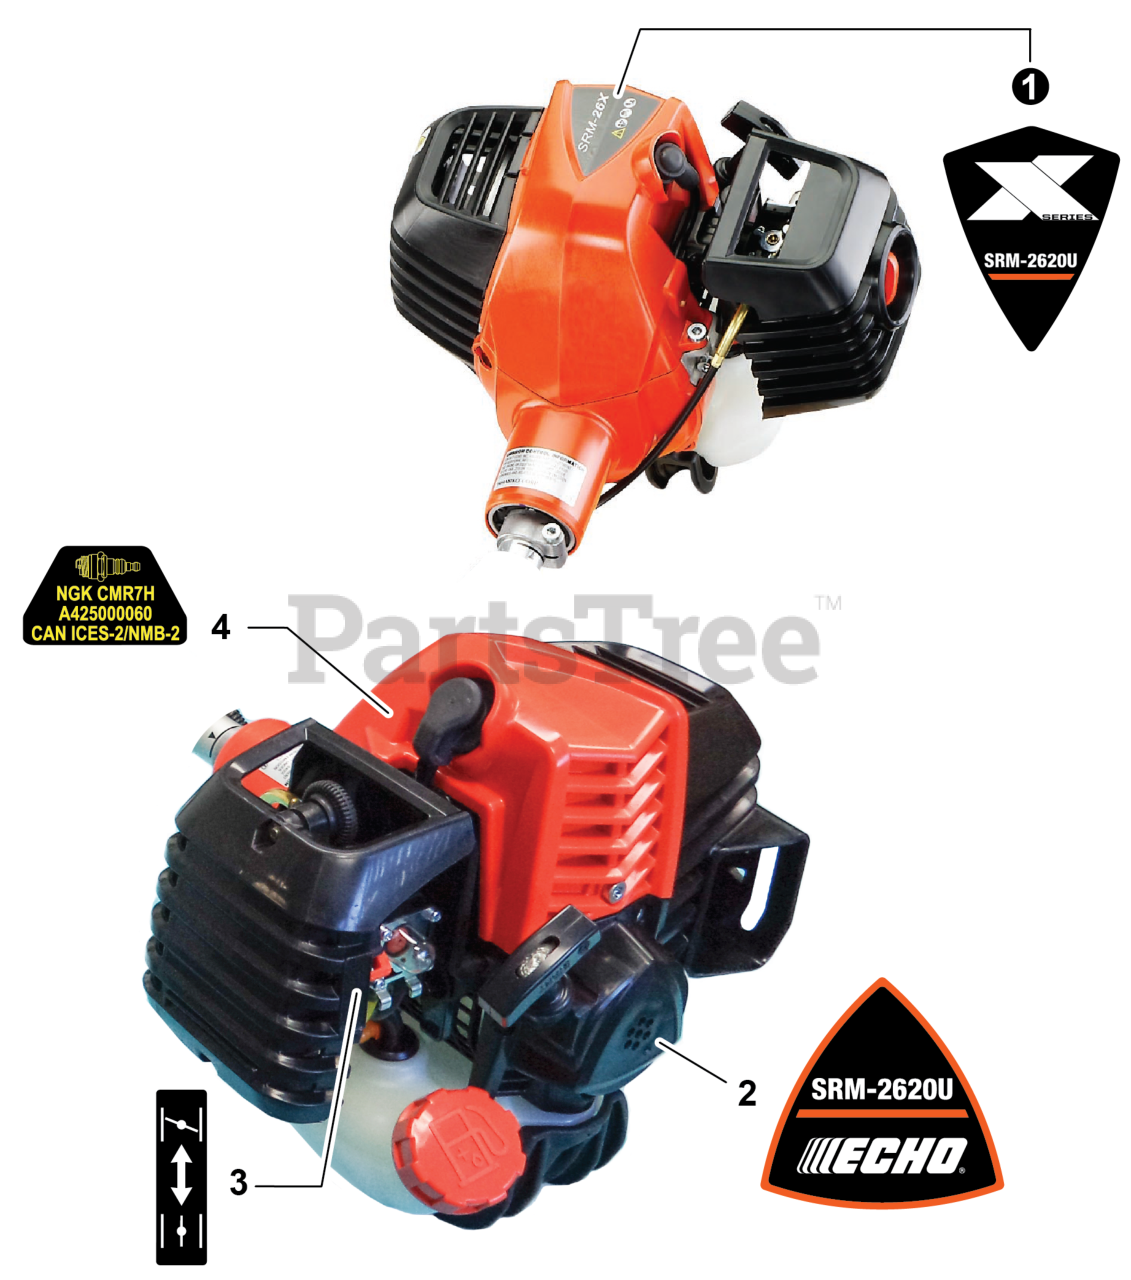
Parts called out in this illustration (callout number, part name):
1	LABEL - MODEL SRM-2620U
2	LABEL - STARTER - SRM-2620U
3	LABEL - CHOKE
4	LABEL - SPARK PLUG - CMR7H
